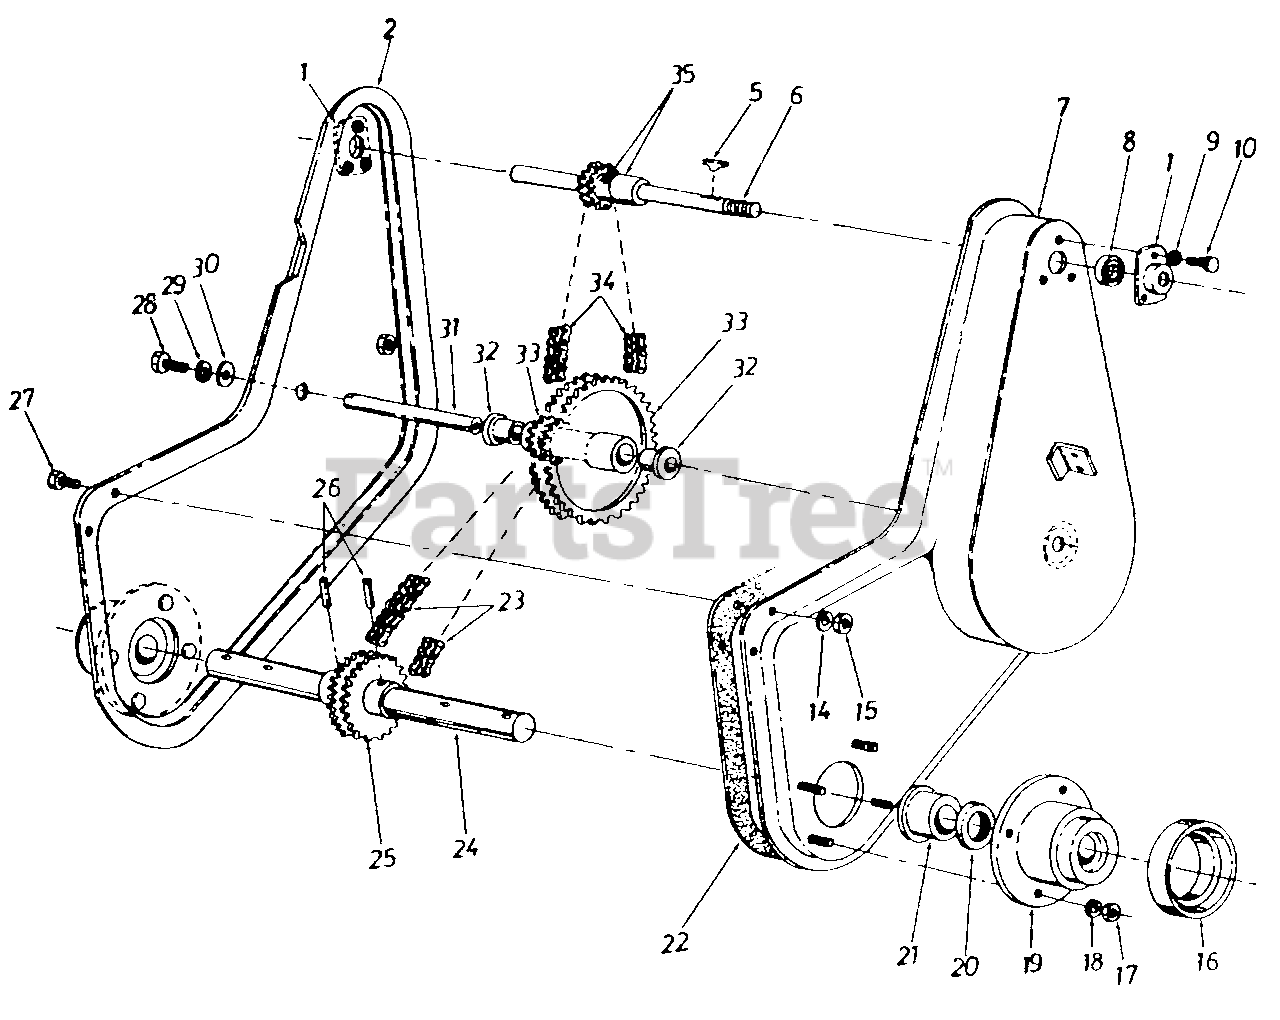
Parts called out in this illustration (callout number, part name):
1	Bearing Housing 1.375" Dia.
6	Input Shaft Assembly
9	L-Wash. 1/4" I.D.*
10	Hex Bolt 1/4-20 x .62" Lg.*
14	L-Wash. 1/4" I.D.*
15	Hex Cent. L-Nut 1/4-20 Thd.
16	Dust Cap Cover
17	Hex Cent. L-Nut 5/16-18 Thd.
18	L-Wash. 5/16" I.D.*
19	Cast Bearing Housing
21	Flange Bearing 1.25" I.D. x 1.75" O.D.
23	Roller Chain #40-2 x 34.0" Lg.
24	Tine Shaft
25	Double Sprocket T24-2 Teeth 1/2" Pitch
26	Spiral Pin 3/8" Dia. x 2.00" Lg.
27	Hex Bolt 1/4-20 x .62" Lg.*
28	Hex Bolt 5/16-18 x .75" Lg.*
29	L-Wash. 5.16" I.D.*
30	Fl-Wash. 5/6" I.D.
31	Sprocket Shaft
32	Flange Bearing .62" I.D. x .75" O.D.
33	Double Sprocket Assembly
34	Roller Chain #35-2 x 36.75" Lg.
35	Spacer 5/8" I.D. x 7/8" O.D.
